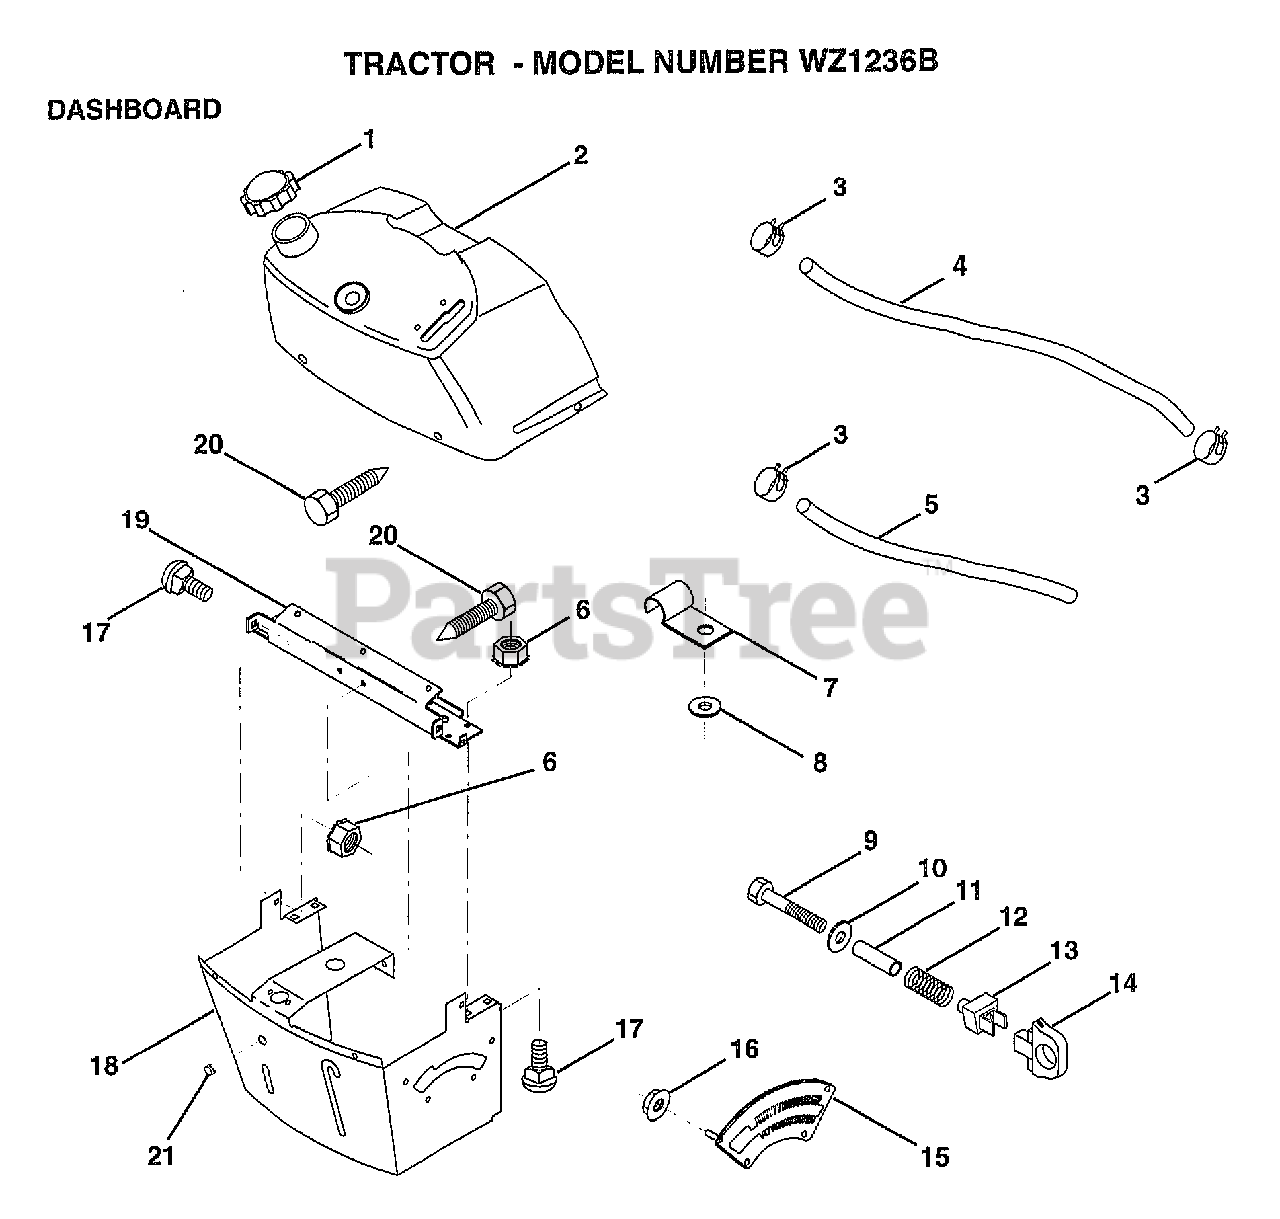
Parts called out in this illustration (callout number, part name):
1	CAP BLK FUEL LR
2	TANK.ASM.DASH.LR
3	HOSE CLAMP
5	FUEL LINE T
6	NUT HXKEP 1/4X20
7	CLIP T
8	WASHER PM
9	BOLT
11	SPACER SPLIT
12	SPRING M
13	"KNOB,HGT RETAINER"
14	KNOB
15	ADJUSTER QUAD
16	NUT
17	BOLT
18	SUPT ASSY DASH
19	CROSS BRACE
20	SCREW.1/4-20X1/2
21	PLUG DOME
